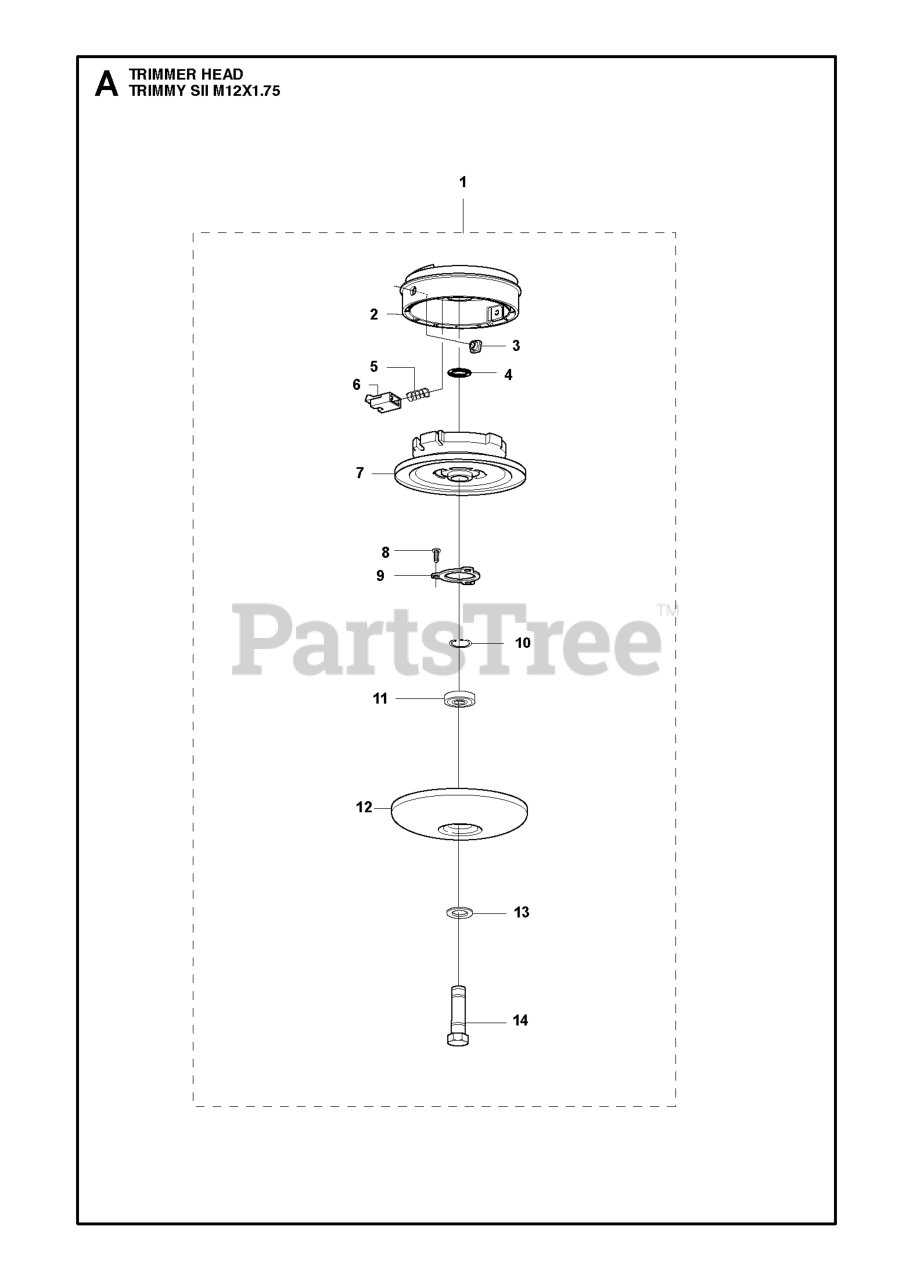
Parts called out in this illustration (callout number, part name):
10	RETAINING RING
11	Ball Bearing 6003-2rs1
12	Base Plate
